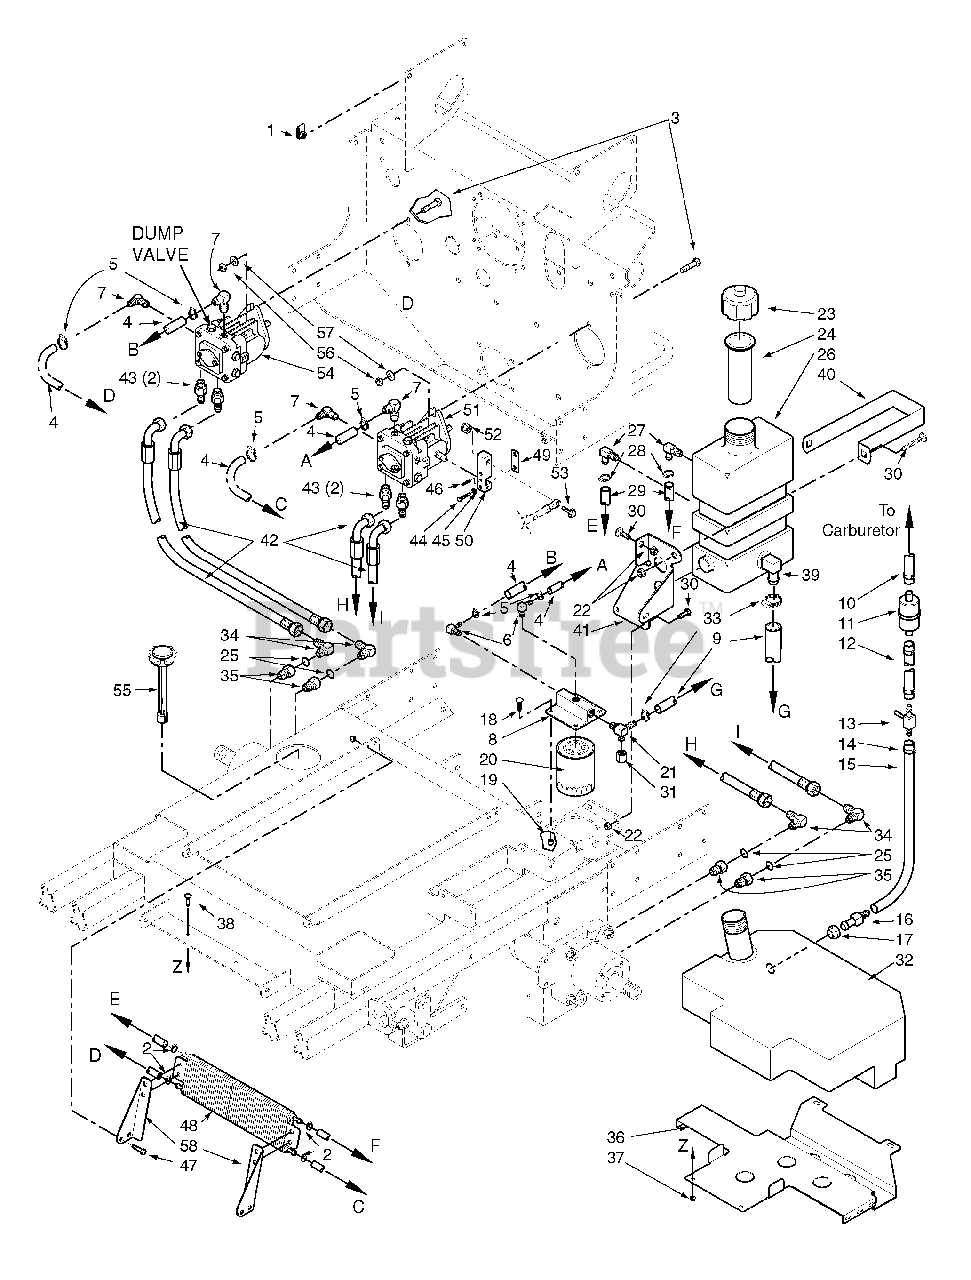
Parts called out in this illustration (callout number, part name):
1	U-Nut 1/4-20
2	Hose Clamp, 0.69 dia.
3	Bolt, Hex Head 1/4-20 x 2.0"
4	Hose, 3/8" ID Pushlock
5	Clamp, Hose 1/2"
6	Elbow, 90 Degree - 1/4 NPT x 3/8 Hose
7	Elbow, 90 Degree - 9/16 O-ring x 3/8 Hose
8	Oil Filter Base
9	Hose Assembly, 1/2" ID (Tank to Filter Base)
10	Fuel Hose to Carb.
11	Fuel Filter
12	Fuel Hose, 1/4" ID.
13	Valve, Shutoff Kawasaki
14	Clamp, Fuel Hose
15	Fuel Hose, 1/4" ID.
16	Hose Fitting
17	Bushing
18	Bolt, Hex Head 5/16-18 x 1.0" Zinc
19	Nut, Serrated Flange 5/16-18
20	Oil Filter
21	Tee, 3/4 O-ring x JIC x 1/2" Hose
22	Nut, Hex Elastic Stop 1/4-20
23	Cap, Hydraulic Tank
24	Insert, Filler Neck
25	O-Ring
26	Oil Reservoir Assembly
27	Elbow, 90 Degree .38 Hose
28	Hose Clamp, 0.69 dia.
29	Hose, 3/8" ID, Pushlock
30	Screw, Phillips Head, 1/4-20
32	Fuel Tank Assembly
33	Clamp, Hose
34	Elbow, 90 Degree, 7/8-14 THD
35	Bushing, 7/8-14 JIC x 3/4-16 O-Ring
36	Support Bracket, Fuel Tank
37	Nut, 5/16-18 Serrated Flange
38	Bolt, Carraige 1/4-20 x 3/4"
39	Elbow, 90 Degree
40	Strap, Hydraulic Tank
41	Support Bracket, Hydraulic Tank
42	Hose Assembly, Pump
43	Union, 3/4-16 JIC x 3/4-16 O-ring
44	Bolt, Hex Head, 1/4-20 x 1-14"
45	Lockwasher, 1/4" Spring
46	Roll Pin, Spring 3/16 x 3/4"
47	Bolt, Hex Head 5/16-18 x 3/4"
48	Cooler, Oil
49	Clamp Plate, Pump Control
50	Block, Pump Control
51	Pump, Left Hand, BDP-16A-410
52	Nut, Hex, Elastic Stop 3/8-16
53	Bolt, Hex Head, 3/8-16 x 1-1/4
54	Pump, Right Hand, BDP 16A-307
55	Cap, Fuel Tank W/Gauge
56	Nut, Hex Elastic Stop 3/8-16
57	Flatwasher, 3/8" (.391 x .938 x .105) Grade 8
58	Mounting Bracket - LH, Oil Cooler
